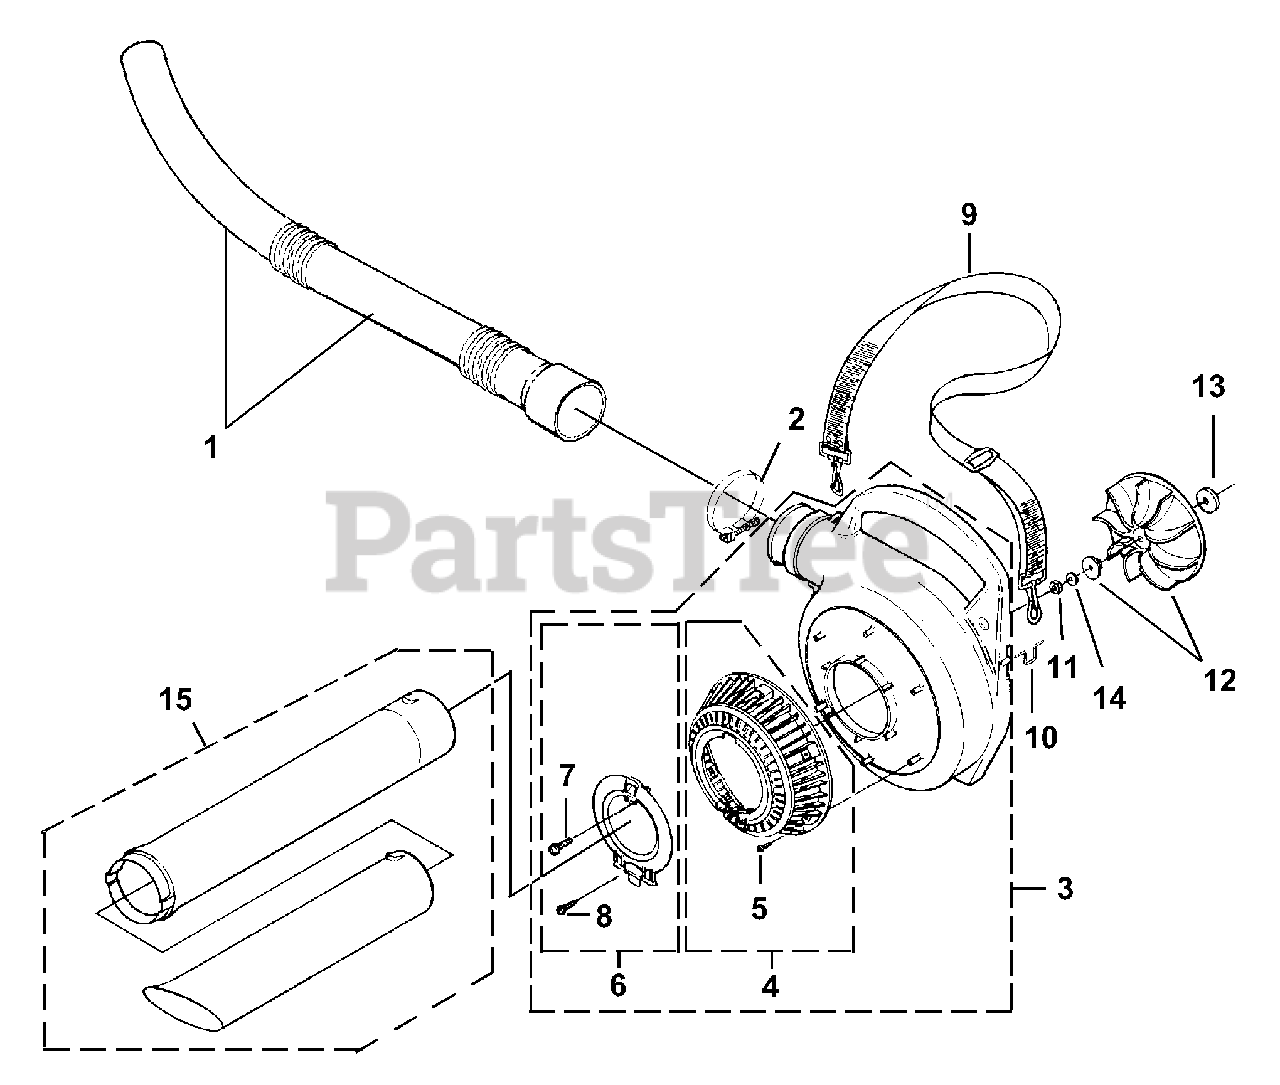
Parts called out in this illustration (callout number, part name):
1	BLOWER TUBE KIT
2	CLAMP w/Fasteners
3	VOLUTE HOUSING KIT
4	BLOWER VAC GRILLE KIT
5	SCREW-Thread Form. (#6 X 3/8")
6	ACCESS DOOR KIT
7	SCREW-Thread Rolling (#10 X 5/8")
8	SCREW-Thread Form. (#8 X 1/2")
9	SHOULDER STRAP
10	WIRE LOOP
11	NUT-Hex (3/8-24)
12	BLOWER FAN KIT
13	WASHER-Flat
14	WASHER-Bellville (3/8")
15	TUBE Kit w/Decals
